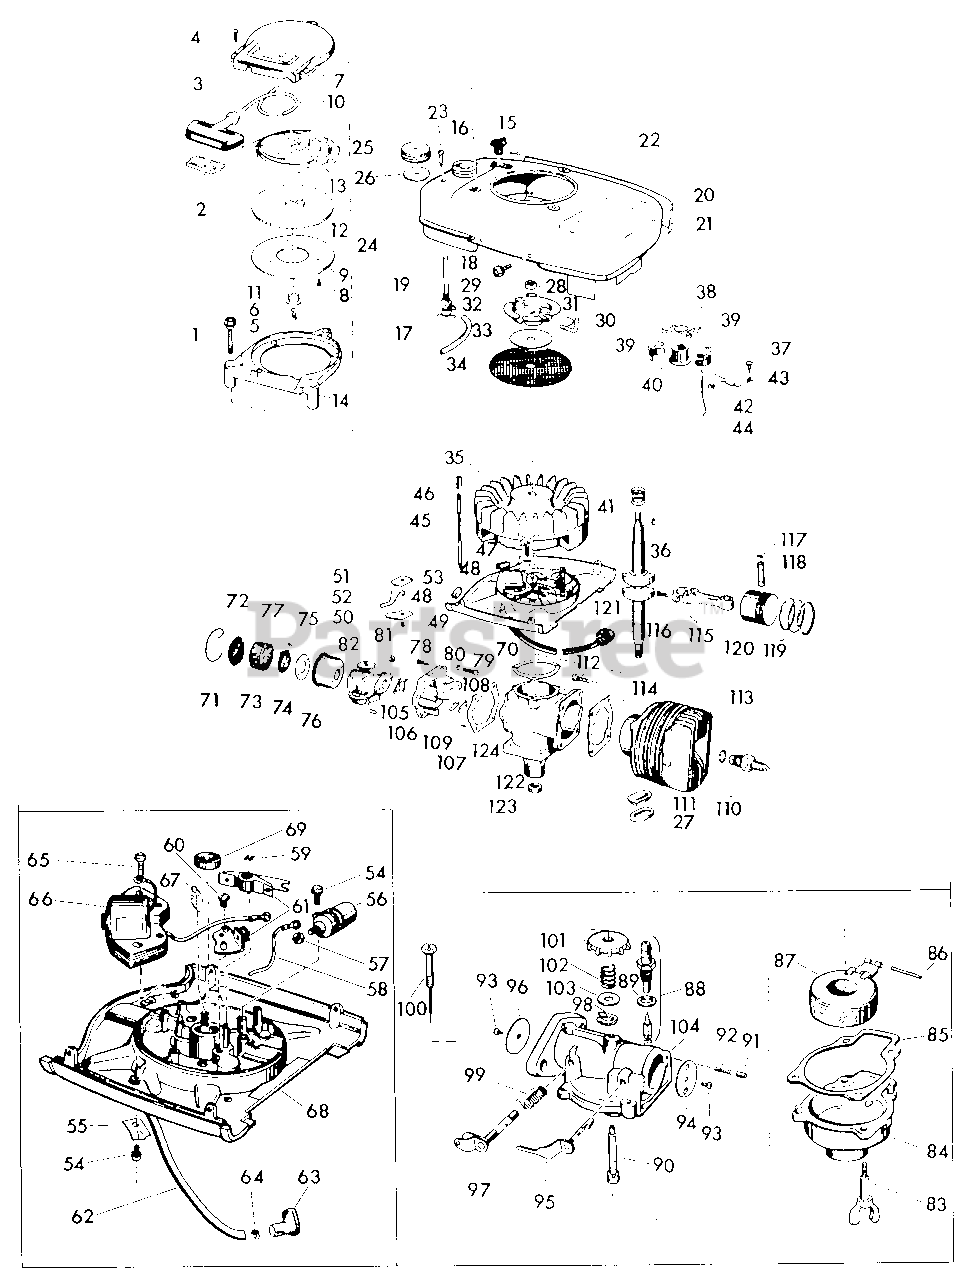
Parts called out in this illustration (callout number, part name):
1	Screw-Starter to Shroud
2	Anchor-Rope
3	Handle-Starter
4	Screw-Starter Cap to Base
5	Screw-Pulley to Cap
6	Washer-Lock, Pulley to Cap
7	Cap-Starter
8	Screw-Pulley Plate
9	Plate-Pulley
10	Rope-Starter
11	Bearing-Pulley
12	Pulley-Rewind
13	Spring-Recoil
14	Base-Starter
15	Pin-Cotter, Choke Knob
16	Knob-Choke Bar
17	Line-Gas
18	Screw-Shroud to Armature Plate
19	Shut-off Valve and Screen Assembly
20	Shroud and Shield Assembly
21	Decal-Instruction
22	Decal-"Lawn-Boy"
23	Screw-Machine
24	Gas Tank Assembly
25	Gas Cap and Gasket Assembly
26	Gasket-Gas Cap
27	Gasket-Exhaust
28	Nut-Flywheel
29	Washer-Lock, Flywheel
30	Pin-Starter
31	Spring-Starter Pin
32	Pulley-Flywheel
33	Washer-Flywheel
34	Screen-Flywheel
35	Flywheel Assembly
36	Key-Woodruff
37	Screw-Governor
38	Yoke-Governor
39	Weight-Governor
40	Collar-Governor
41	Spring-Governor
42	Block-Wear, Governor
43	Governor Lever and Wear Block Assembly
44	Rod-Governor
45	Bar-Choke
46	Sleeve-Choke Bar
47	Screw-Crankcase to Armature Plate
48	Pad-Rubber, Armature Plate
49	Screw-Shut-off Switch
50	Insulator-Shut-off, Lower
51	Insulator-Shut-off, Upper
52	Spring-Shut-Off Switch
53	Armature Plate Assembly
54	Screw-Condenser and Clamp Mounting
55	Clamp-High Tension Lead
56	Condenser Assembly
57	Nut-Condenser Terminal
58	Shut-Off Switch Lead Assembly
59	Clip-Spring, Breaker Post
60	Screw-Breaker Base
61	Breaker Base and Arm Assembly
62	High Tension Lead Assembly
63	Cover-Rubber, Spark Plug
64	Terminal-Spring
65	Screw-Lamination Mounting
66	Coil and Lamination Assembly
67	Wick-Oiler
68	Armature Plate, Bearing and Oil Seal Assembly
69	Seal-Oil
70	Gasket-Crankcase to Armature Plate, .005 in.
70	Gasket-Crankcase to Armature Plate, .010 in.
71	Clip-Air Filter
72	Screen-Air Filter (Large)
73	Element-Air Filter
74	Screen-Air Filter (Small)
75	Plate-Back-Up, Filter Cup
76	Cup-Air Filter
77	Screw-Air Filter
78	Screw-Reed Plate to Crankcase
79	Screw-Reed Plate to Carburetor
80	Washer-Reed Plate to Carburetor Screw
81	Nut-Stop, Reed Plate to Carburetor Screw
82	Carburetor Assembly
83	Screw-Wing
84	Float Chamber
85	Gasket-Carburetor Body to Float Chamber
86	Pin-Float Arm Hinge
87	Float and Arm Assembly
88	Float Valve-Seat and Washer Assembly
89	Washer-Float Valve Seat
90	Nozzle
91	Plug-Choke Friction
92	Spring-Choke Friction
93	Screw-Choke and Throttle Disc
94	Disc-Choke
95	Choke Shaft and Lever Assembly
96	Disc-Throttle
97	Throttle Shaft and Ring Assy.
98	Grip-Ring
99	Spring-Throttle Shaft
100	Needle Assembly
101	Knob-Needle Valve
102	Spring-Needle Adjustment
103	Washer-Needle Adjustment
104	Carburetor Body
105	Gasket-Carburetor
106	Reed Plate Assembly
107	Screw-Reed to Reed Plate
108	Plate-Back-Up, Reed
110	Spark Plug and Gasket
111	Sleeve-Exhaust Gasket
112	Screw-Cylinder to Crankcase
113	Cylinder and Sleeve Assembly
114	Gasket-Cylinder to Crankcase
115	Connecting Rod Assembly
116	Screw-Connecting Rod
117	Ring-Spring
118	Pin-Wrist
119	Ring-Piston
121	Crankshaft
122	Crankcase, Oil Seal and Reed Plate Gasket Assembly
123	Seal-Oil
124	Gasket-Reed Plate to Crankcase
